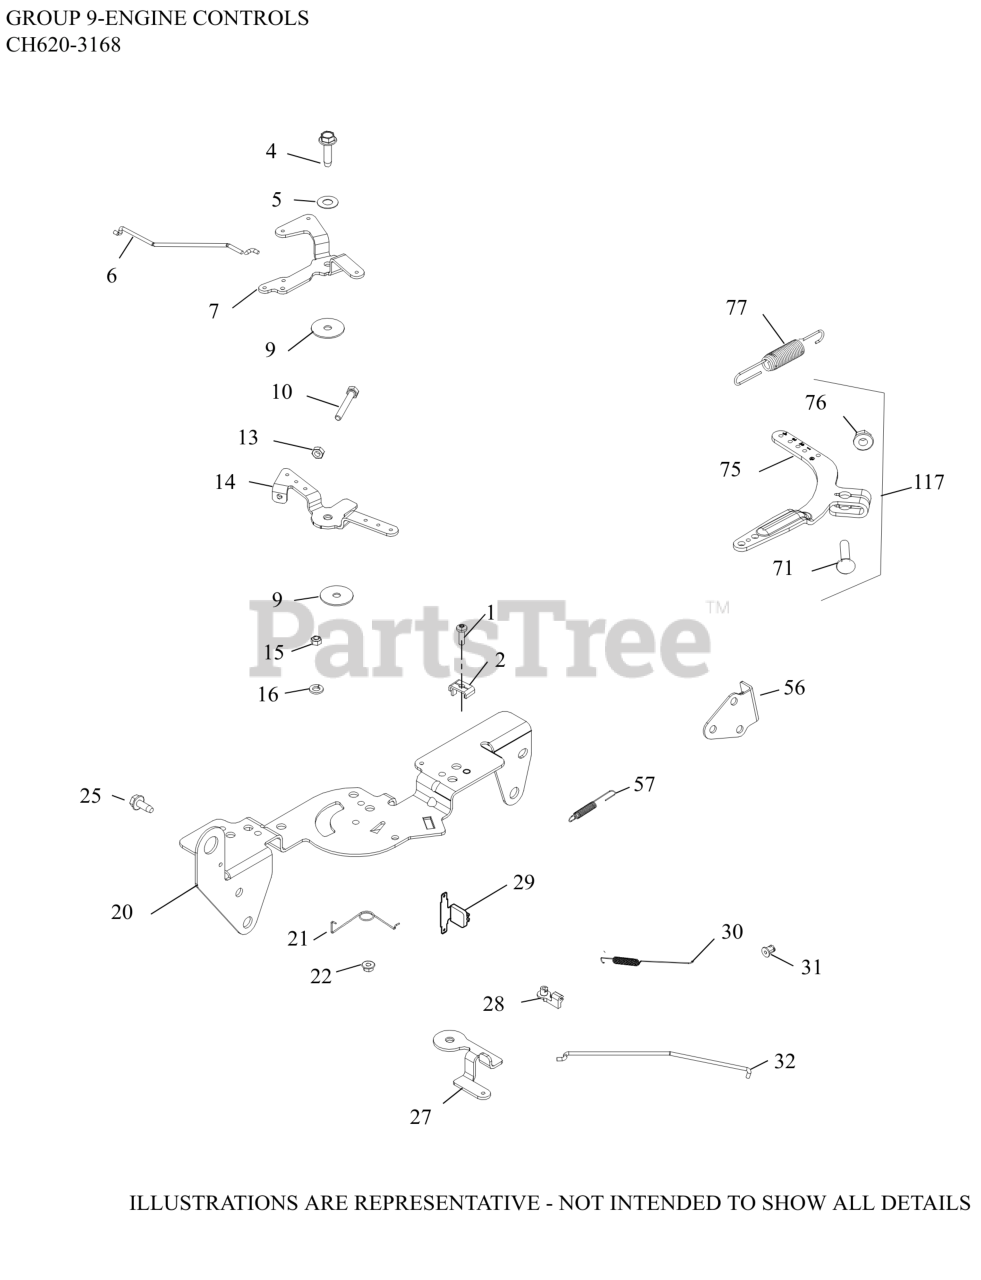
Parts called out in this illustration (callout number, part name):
1	SCREW, THREAD FORMING
2	CLAMP, CABLE CABLE
4	SCREW, THD FRM-USE 25 086 473-S
5	WASHER, SPRING 1/4"
6	LINKAGE, CHOKE
7	LEVER, CHOKE
9	WASHER, FLAT 5.5 MM
10	SCREW, CAP M4X.7X30
13	NUT, M4X0.7
14	LEVER, THROTTLE CONTROL
15	NUT, FLG M5X.8
16	WASHER, SPRING LOCK 1/4"
20	BRACKET, CONTROL
21	SPRING, CHOKE RETURN
22	NUT, LOCK M5X.8
25	SCREW, THREAD FORMING
27	LEVER, THROTTLE ACTUATOR
28	BUSHING, THROTTLE LINKAGE
30	SPRING, LINKAGE
31	BUSHING, LINKAGE RETAINING
32	LINKAGE, THROTTLE
57	SPRING, THROTTLE LIMITER
71	BOLT, RD HD SQ NECK M6X1.0X25
75	LEVER, GOVERNOR - (#2409069S)
76	NUT, FLG M6X1.0
77	SPRING, GOVERNOR (BLUE)
117	LEVER, GOVERNOR ASSEMBLY
